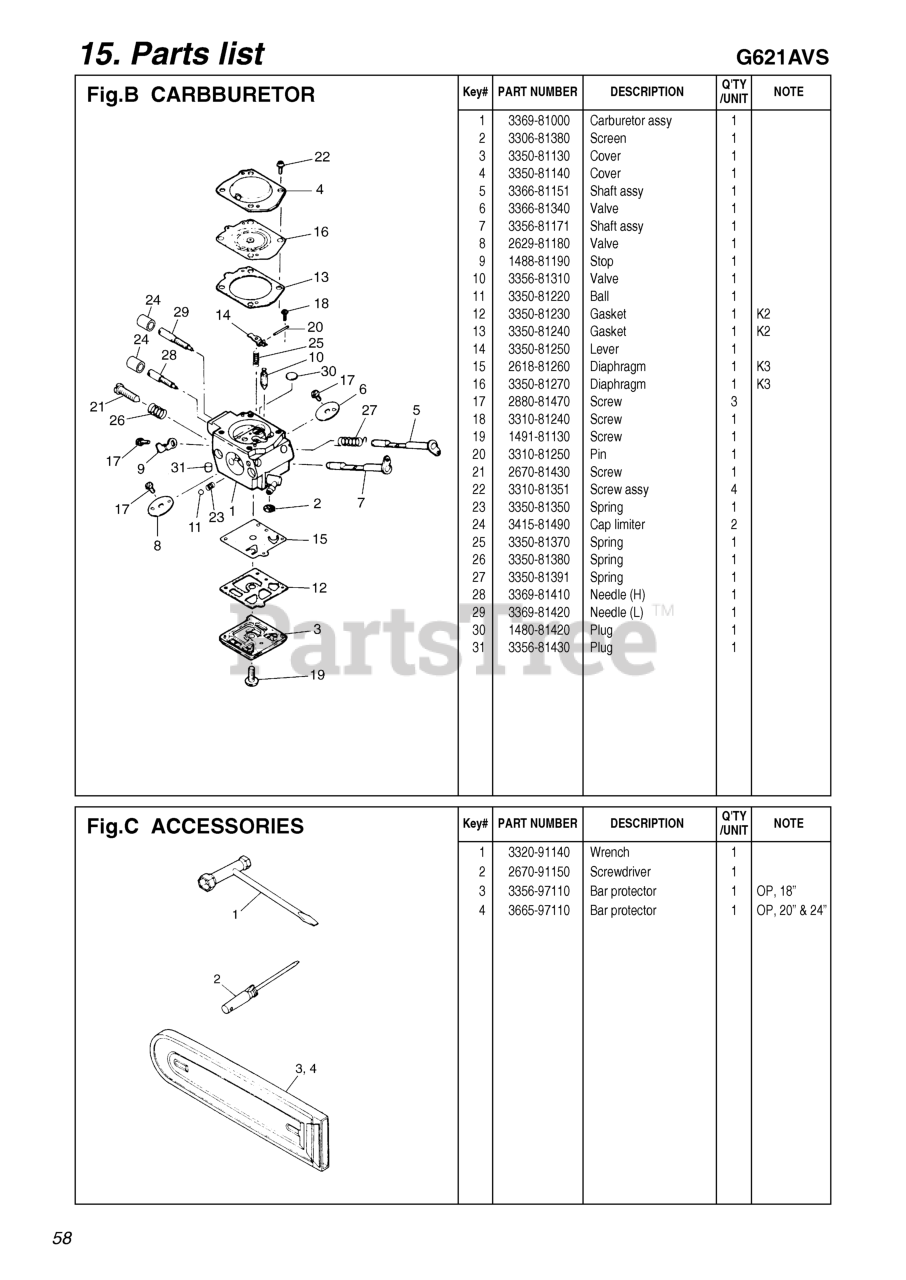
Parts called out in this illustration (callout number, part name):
1	CARBURETOR
5	SHAFT ASSY
7	SHAFT ASSY
10	VALVE
11	BALL
15	DIAPHRAGM
16	DIAPHRAGM
19	SCREW
20	PIN
22	SCREW ASSY
23	SPRING
24	CAP, LIMITER
28	NEEDLE (H)
29	NEEDLE (L)
A2	SCREWDRIVER
A3	BAR PROTECTOR
A4	BAR PROTECTOR
